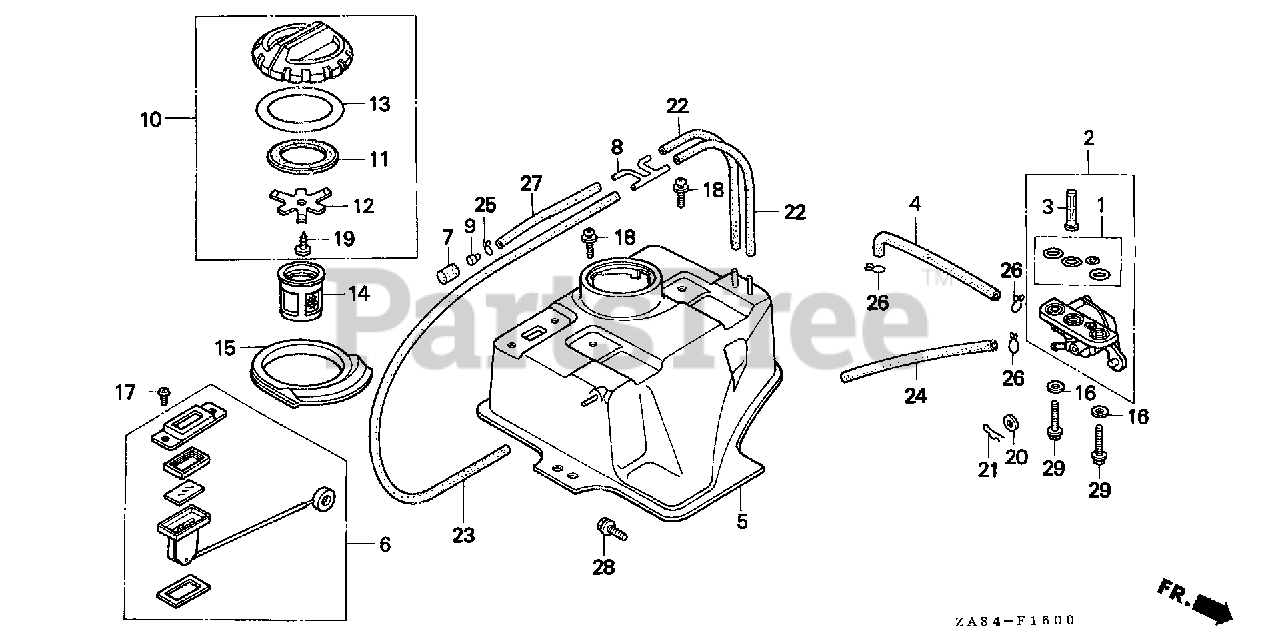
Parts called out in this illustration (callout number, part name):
1	GASKET SET, VALVE
2	PETCOCK ASSY.
3	SCREEN, FUEL STRAINER
4	TUBE, FUEL (4.5)
5	TANK, FUEL
6	METER ASSY., FUEL
7	ELEMENT, HANDLE BREATHER
8	JOINT, BREATHER TUBE
9	FILTER, GASOLINE
10	CAP ASSY., FUEL FILLER
11	GASKET, FUEL FILLER CAP
12	SPRING, PLATE
13	WASHER (58MM)
14	FILTER, FUEL
15	GUIDE, TANK CAP
16	GASKET, FIBER (6MM)
17	SCREW, PAN (5X8)
18	SCREW-WASHER (5X12)
19	SCREW, TAPPING (6X16)
20	WASHER, PLAIN (6MM)
21	PIN, LOCK (6MM)
22	BULK HOSE, FUEL (3.5X3000) (3.5X120)
23	BULK HOSE, FUEL (3.5X3000) (3.5X445)
24	BULK HOSE, FUEL (4.5X3000) (4.5X210)
25	CLIP, TUBE (B7)
26	CLIP, TUBE (B8)
27	BULK HOSE, VACUUM (3.5X1000) (3.5X55)
28	BOLT, FLANGE (6X10)
29	BOLT, FLANGE (6X20)
